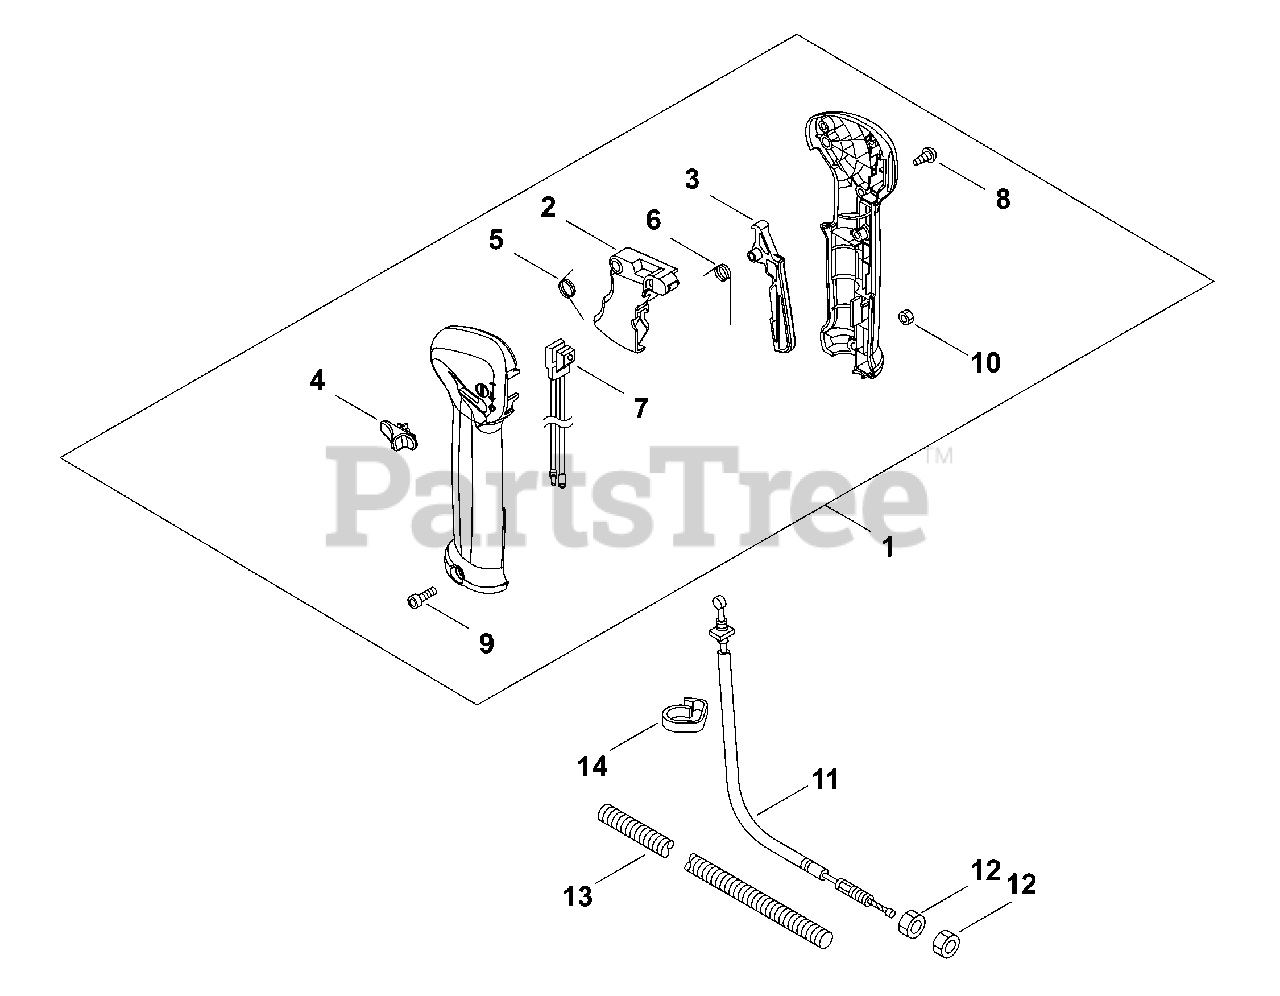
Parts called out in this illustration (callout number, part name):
1	THROTTLE CONTROL ASSY
2	TRIGGER, THROTTLE
3	LOCKOUT, THROTTLE
5	SPRING, TORSION
6	SPRING, TORSION
7	SWITCH, ON-OFF
8	SCREW 4×16
11	CABLE, THROTTLE
